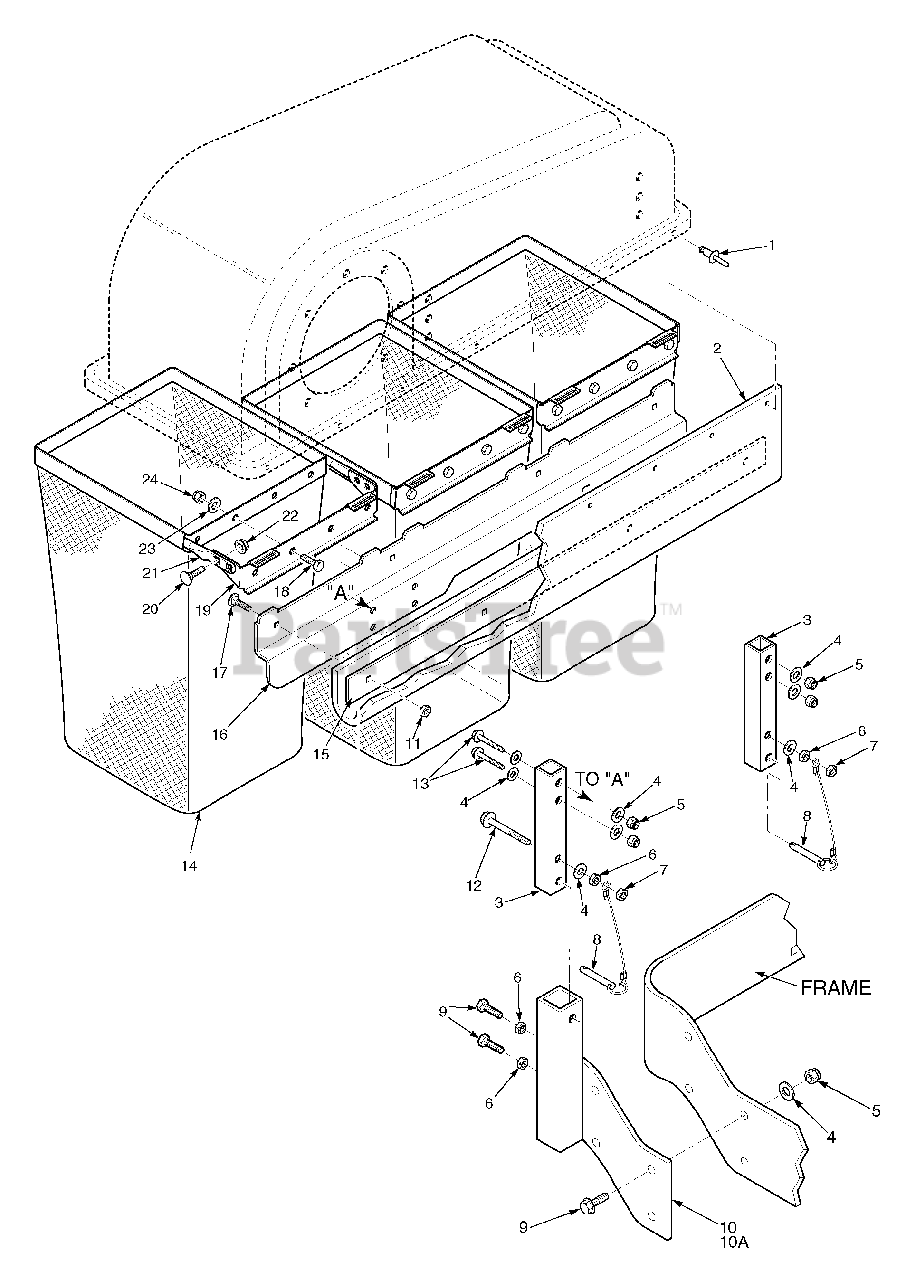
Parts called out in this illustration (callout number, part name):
1	Pop Rivet, 3/16 x .652
2	Seal, Hood
3	Tube, Upright
4	Flatwasher, 3/8-.391 x .938 x .105
5	Nut, Elastic Stop 3/8-16
6	Nut, 3/8-16
7	Hex Lock Nut, 3/8-16
8	Pin, Ring 1/2 x 2-1/4"
9	Bolt, Hex Head 3/8-16 x 1"
10	Mounting Bracket Weldment RH
10A	Mounting Bracket Weldment LH
11	Lock Nut, 1/4-20 Center
12	Bolt, Hex Head 3/8-16 x 2-1/4"
13	Bolt, Hex Head 3/8-16 x 2-1/2"
14	Bag Assembly, GC-STT
15	Retainer, Seal
16	Support, Bag Frame
17	Bolt, Carr. 1/4-20 x 3/4"
18	Bolt, Hex Head 5/16-18 x 3/4"
19	Mount, Bag Frame Tube
20	Bolt, Carr. 5/16-18 x 3/4"
21	Tube, Bag Support
22	Nut, Serr. Flange 5/16-18
23	Flatwasher, 5/16-.375 x .875 x .083
24	Nut, Elastic Stop 5/16-18
